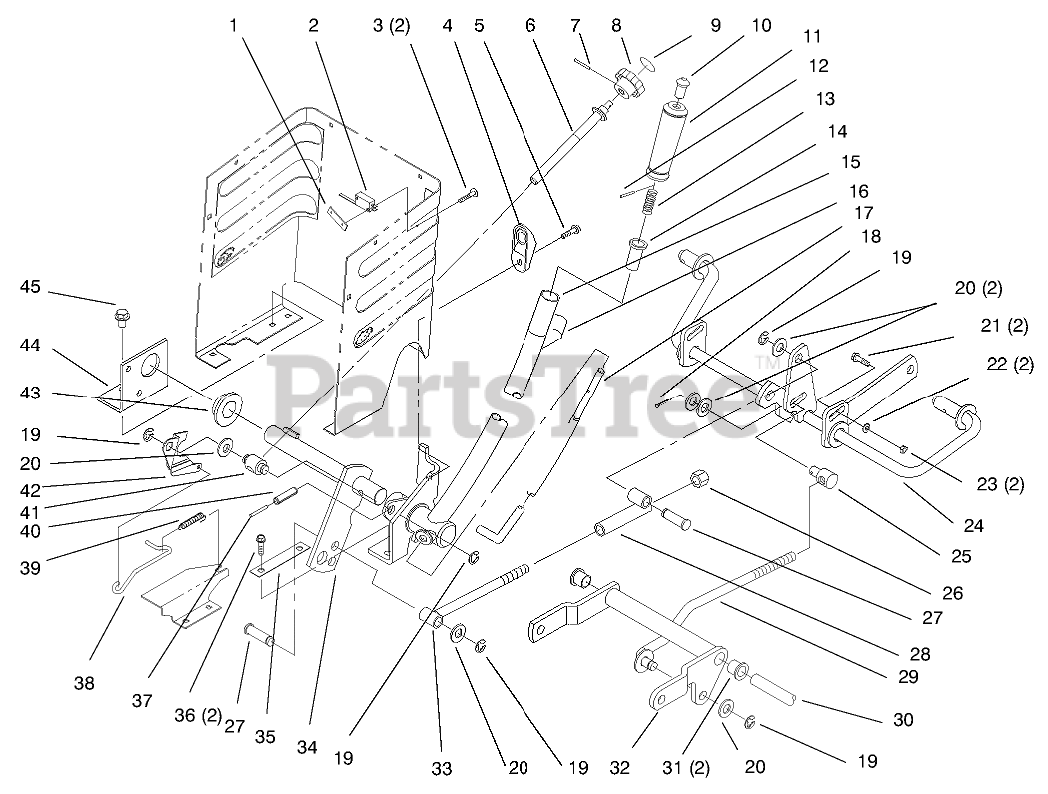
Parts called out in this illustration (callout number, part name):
1	NUT-SPEED
2	SWITCH-MICRO
3	SCREW-PPHTF
4	WEDGE - HOC
5	SCREW-HWH
6	ROD - HOC
7	PIN-SPIROL
9	DECAL-HEIGHT KNOB
18	PIN-COTTER
19	RING-RETAINING, EXTERNAL
20	WASHER-FLAT
21	BOLT-CARR
22	WASHER-FLAT
23	NUT-LOCK, NI
24	SHAFT-GAGE
25	ROD-TRUNNION LIFT
26	NUT-LOCK, NI
30	SHAFT-PIVOT, PEDAL
31	BUSHING-FLANGE
32	ARM-PIVOT
34	SHAFT-LIFT
36	SCREW-HWHTF
37	PIN-SPRING
38	ROD - HOC INDICATOR
39	SPRING - EXTENSION
40	PIN-ROLL
41	TRUNNION
42	PLATE - HOC GAGE
43	BEARING-FLANGE
44	BRACKET-PIVOT, LINKAGE
45	SCREW-HWHTF
